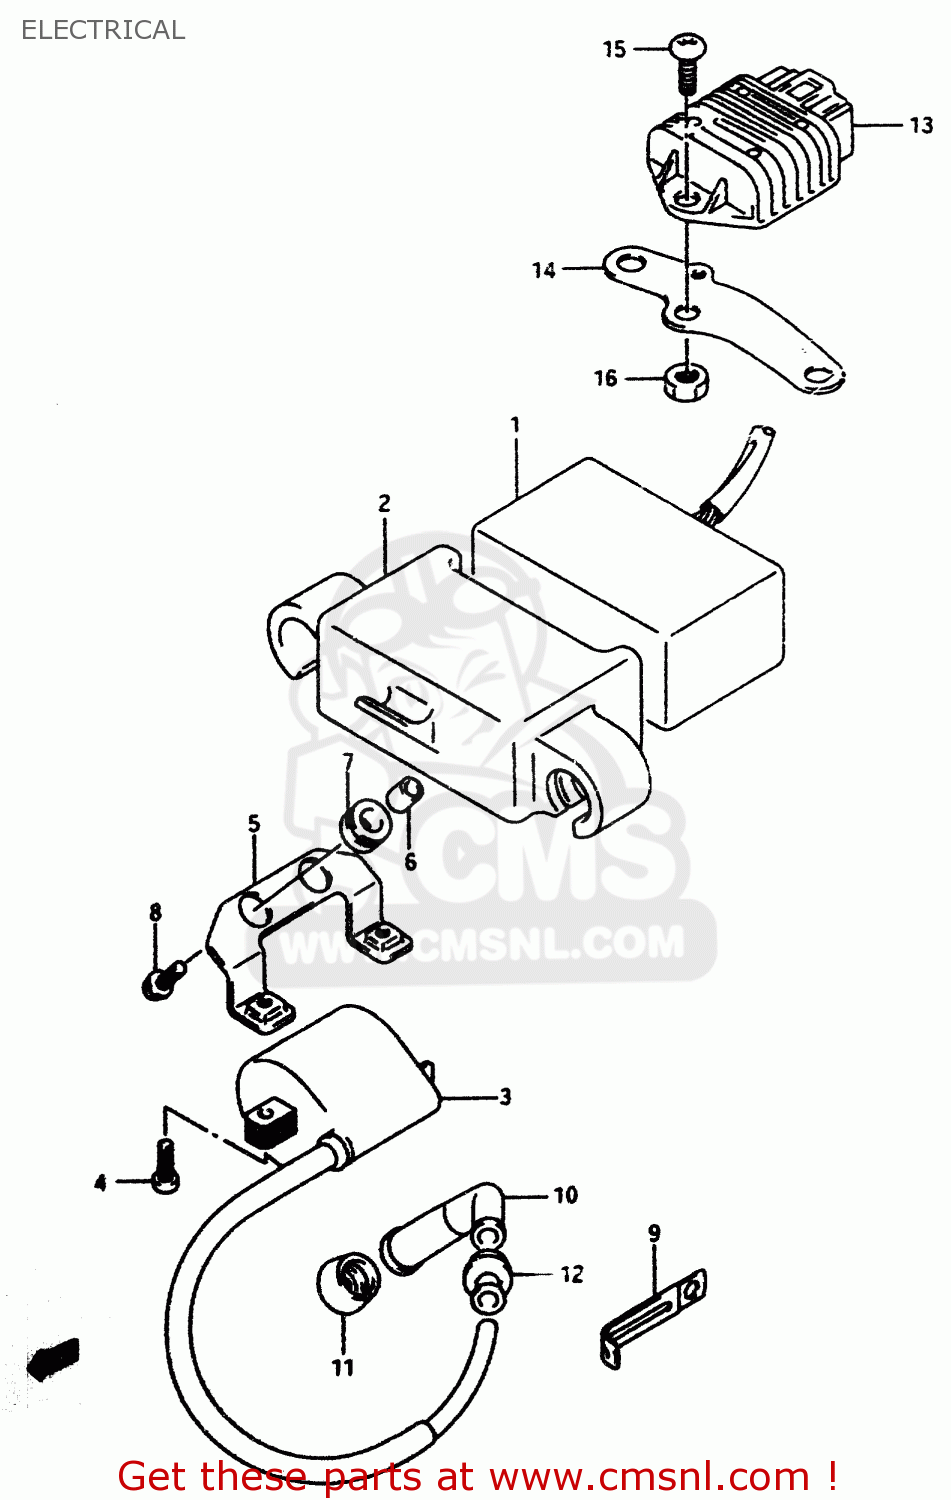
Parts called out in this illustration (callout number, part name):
1	CDI UNIT
2	CUSHION,CDI UNIT
3	COIL ASSY,IGNITION
4	SCREW, 6X20
5	BRACKET,IGNITION COIL
6	SPACER(6.5X9X6.7)
7	CUSHION
8	BOLT
9	CLAMP(L:45)
10	CAP,SPARK PLUG
11	SEAL,SPARK PLUG
12	SEAL,HIGH TENSION CORD
13	REGULATOR ASSY
14	BRACKET,REGULATOR
15	SCREW 6X12
16	NUT 6MM
